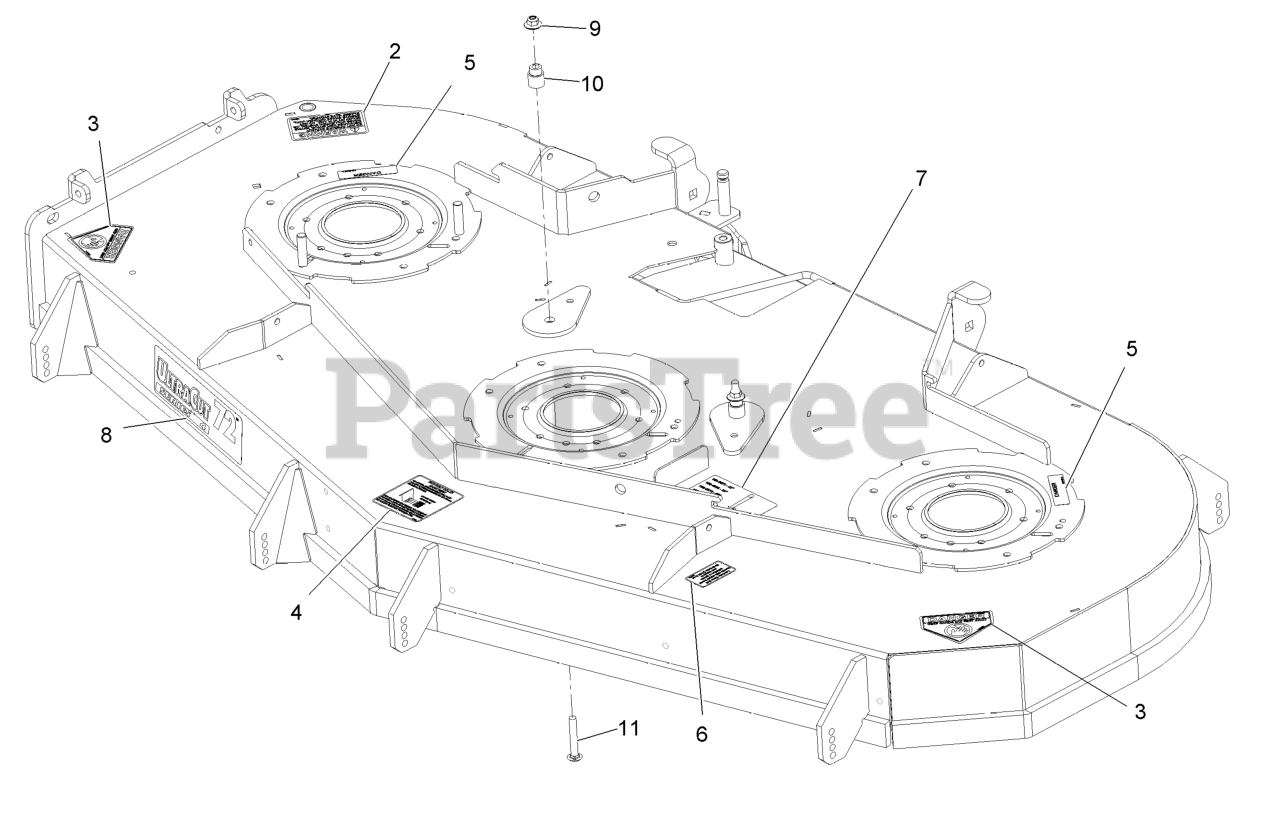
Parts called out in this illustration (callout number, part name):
2	DECAL-WARNING, DISCHARGE
3	DECAL-DANGER
4	DECAL,ANTISCALP
5	DECAL-COVER, MISSING
6	DECAL,BOLT TORQUE
7	DECAL,BELT ROUTING
8	DECAL,ULTRACUT 72 SERIES
9	Nut-Nyloc 3/8-16 Flg
10	BUSHING-IDLER
11	SCREW-CARR
